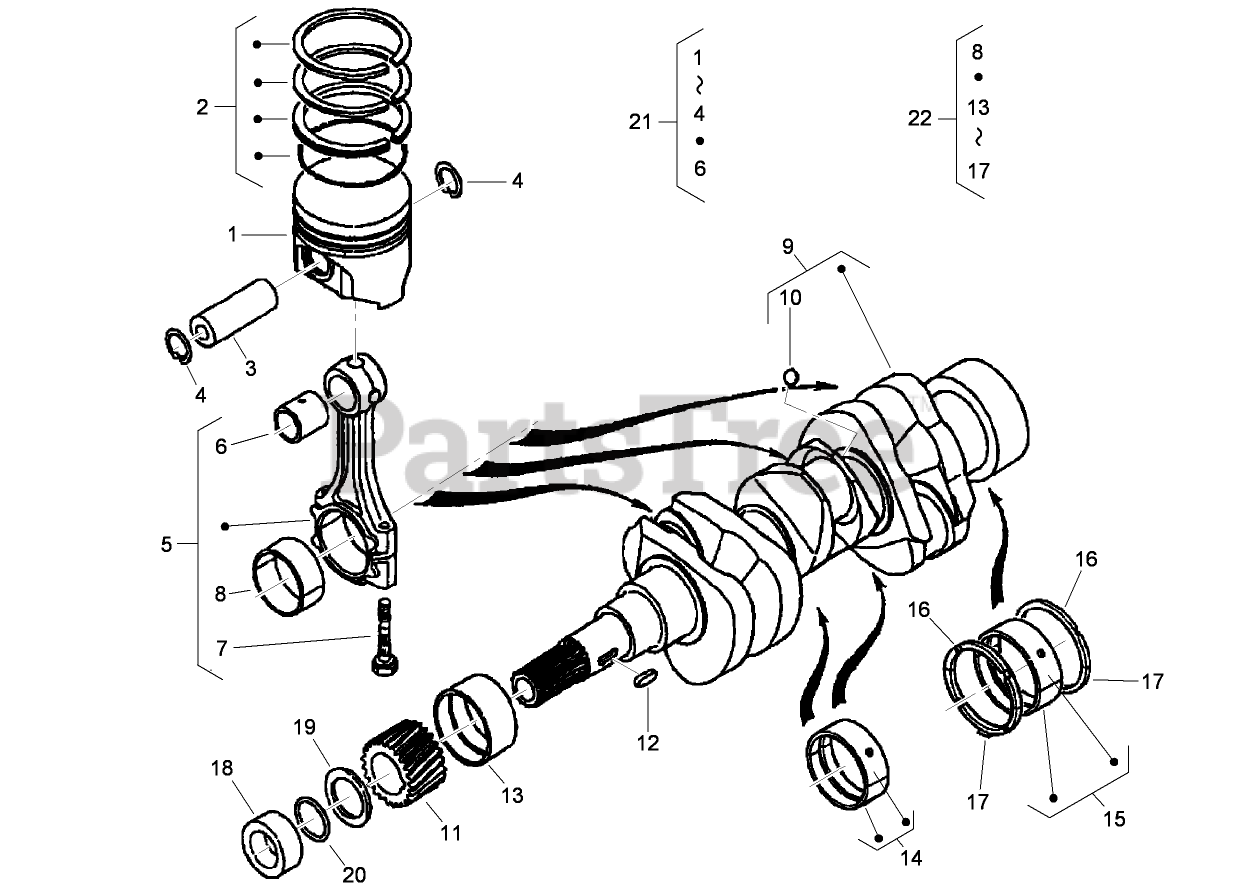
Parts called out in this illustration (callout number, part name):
1	PISTON (STD)
1	PISTON (+.25MM)
2	PISTON RING ASM (STD)
2	PISTON RING ASM (+.25MM)
3	PIN-PISTON
4	CIRCLIP-INTERNAL
5	CONNECTING ROD ASM
6	BUSHING-PIN, PISTON
7	BOLT-ROD, CONNECTING
8	METAL-CRANKPIN (-0.20mm)
8	METAL-CRANKPIN (-0.40mm)
8	METAL-CRANKPIN (STD)
9	CRANKSHAFT
11	GEAR-CRANKSHAFT
12	KEY-FEATHER
13	METAL-CRANKSHAFT (STD)
13	METAL-CRANKSHAFT (-.0.20MM)
13	METAL-CRANKSHAFT (-0.40MM)
14	CRANKSHAFT METAL ASM (STD)
14	CRANKSHAFT METAL ASM (-0.20MM)
14	CRANKSHAFT METAL ASM (-0.40mm)
15	CRANKSHAFT METAL ASM (STD)
15	CRANKSHAFT METAL ASM (-0.20MM)
15	CRANKSHAFT METAL ASM (-0.40MM)
16	METAL-SIDE (STD)
16	METAL-SIDE (+0.20MM)
16	METAL-SIDE (+0.40MM)
17	METAL-SIDE (STD)
17	METAL-SIDE (+0.20mm)
17	METAL-SIDE (+0.40mm)
18	COLLAR-CRANKSHAFT
19	SLINGER-OIL
20	O-RING
21	PISTON KIT (STD)
21	PISTON KIT (+.25MM)
22	ENGINE METAL KIT
